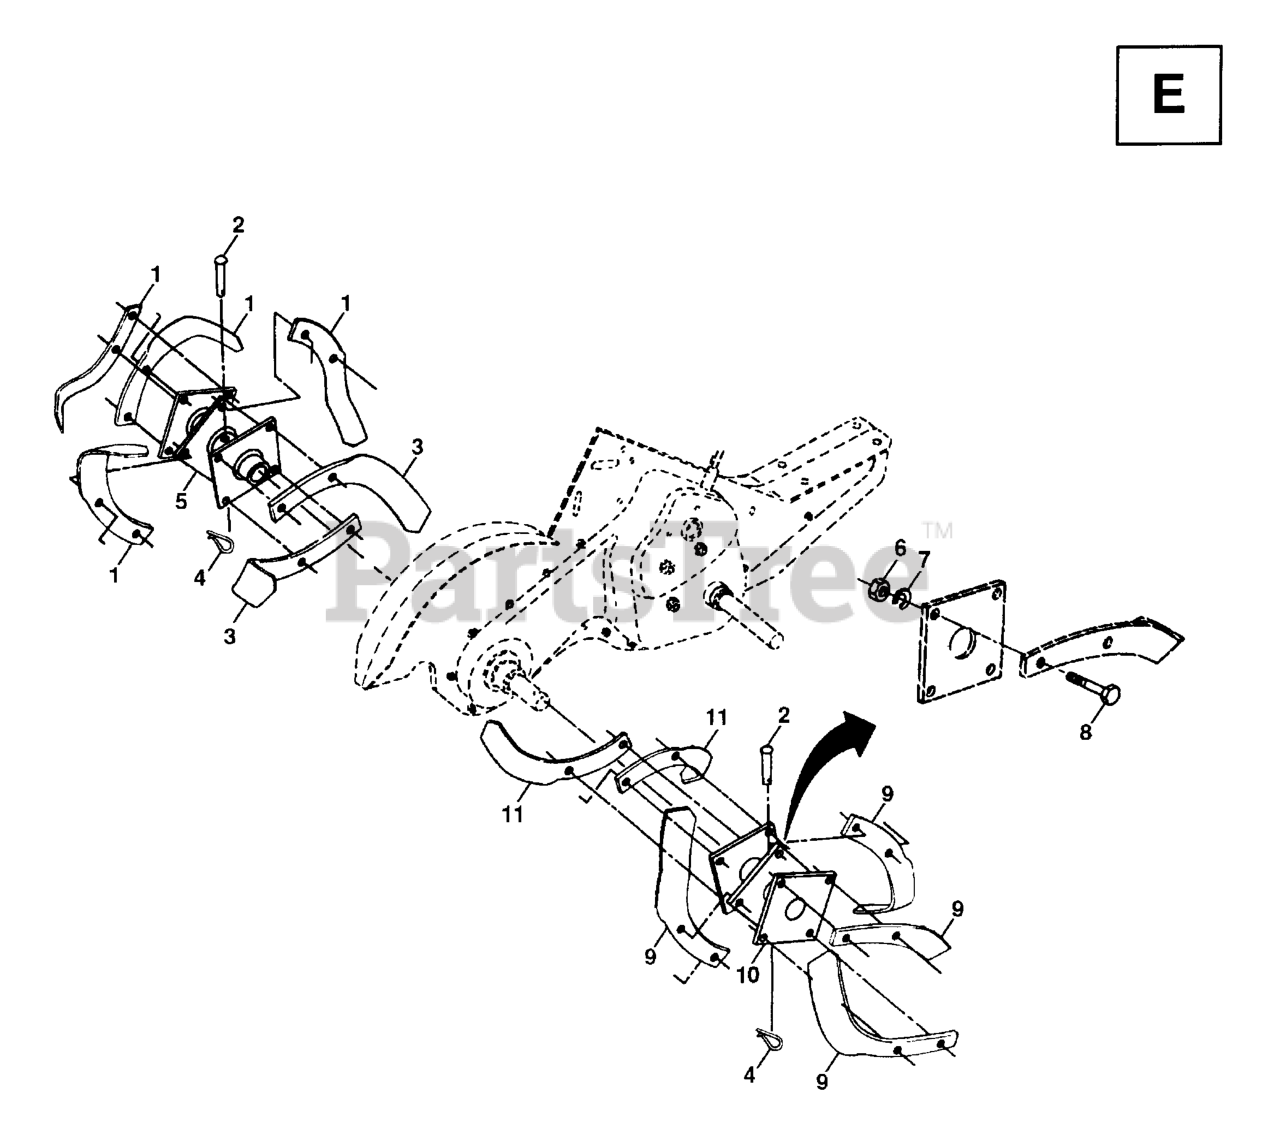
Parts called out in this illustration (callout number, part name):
1	TINE.RH.12"(72R)
2	PIN RETAINING SCREW
3	TINE.LH.12"(72L)
4	SPRING RETAINER
5	HUB.&.PLATE.ASM.LH
6	NUT
7	WASHER, LOCK 3/8
8	BOLT.HEX.001X20.37-24X1.ZINC
9	TINE.LH.12"(72L)
10	HUB & PLATE ASM RH
11	TINE.RH.12"(72R)
